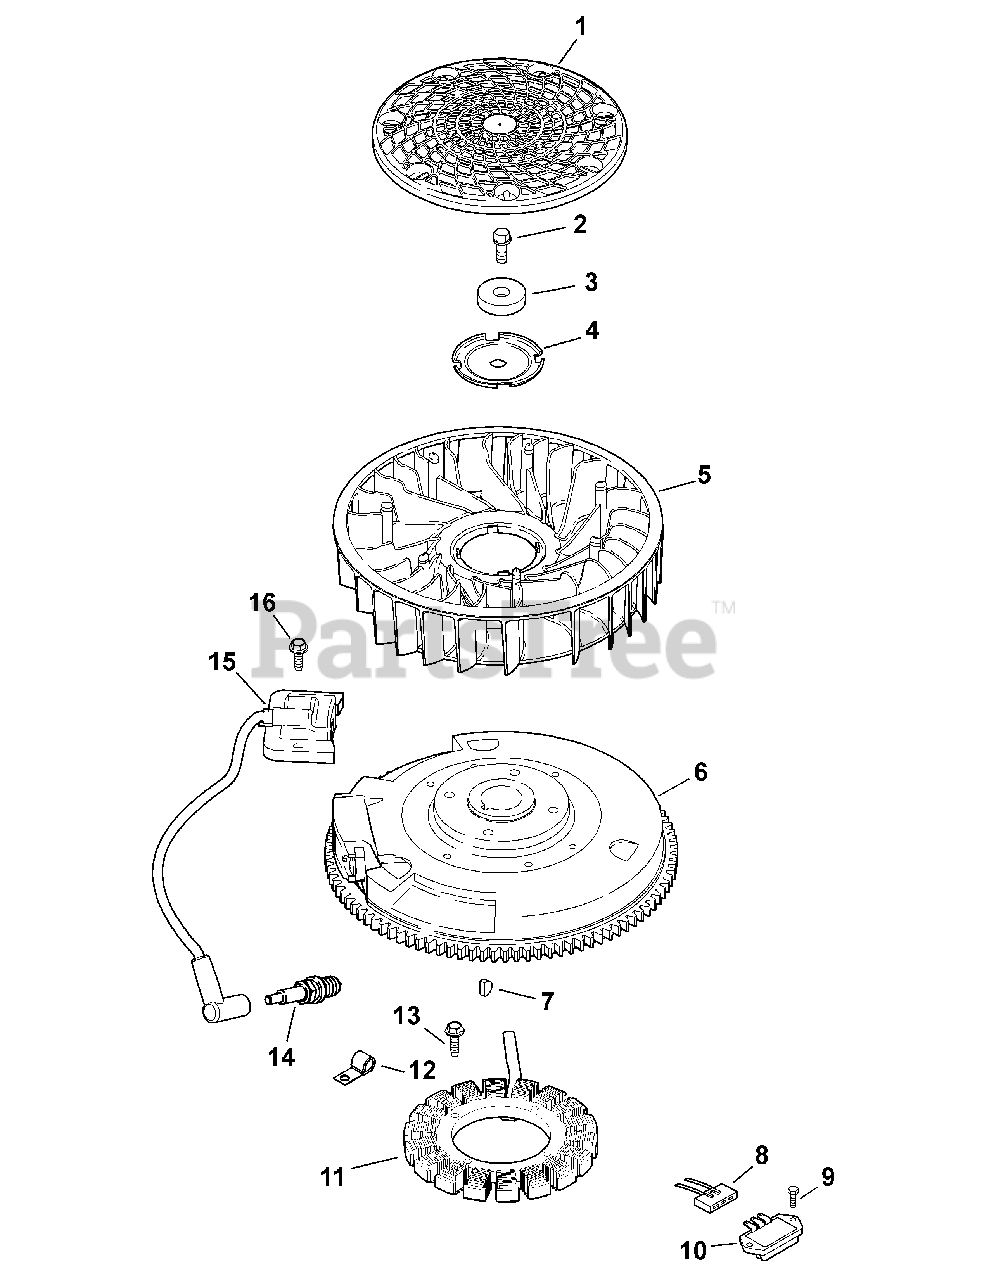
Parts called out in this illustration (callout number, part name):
1	Screen, Grass
2	Screw, Flange, M10 x 1.5 x 45
3	Washer, Flat 13/32
4	Plate, Fan Mounting
5	Fan
6	Flywheel
7	Key, 3/16 x 5/8
8	Connector (3 Contact)
9	Screw, Flange, M5 x 0.8 x 16
10	Rectifier-Regulator
11	Kit, 15 Amp Stator
12	Clip, Cable
13	Screw, Thrd. Frmng M5 x 0.8x 25
14	Plug, Spark
15	Module, Ignition
16	Screw, Flnge Thrd. Frmng M5 x 0.8x 20
